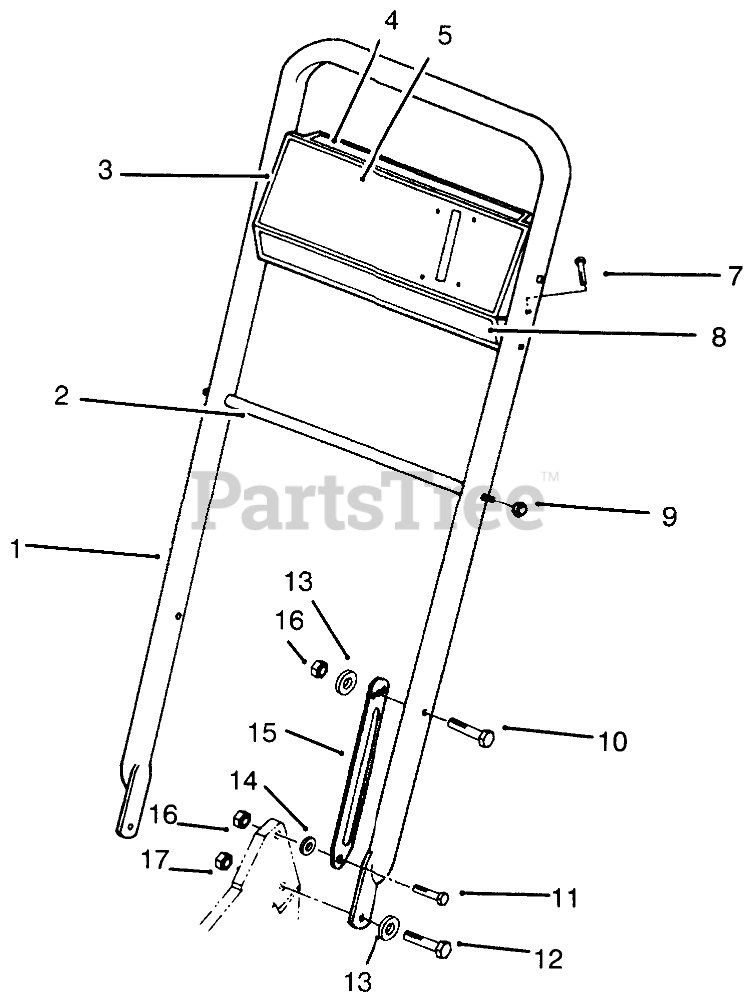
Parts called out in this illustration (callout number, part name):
1	Handle
2	ROD-SUPPORT, BAG
3	Panel-Control (Incl. Ref. #4, 5, & 8)
4	DECAL-PANEL, DANGER
5	DECAL-CONTROL PANEL
7	SCREW-HWHTF
8	DECAL-PANEL, PROLINE
9	NUT-CAP
10	SCREW-HH
11	SCREW-SHOULDER
12	SCREW-HH
13	WASHER-BELLEVILLE
14	SPACER
15	Latch-Handle
16	NUT-LOCK, NI
17	NUT-LOCK, NI
